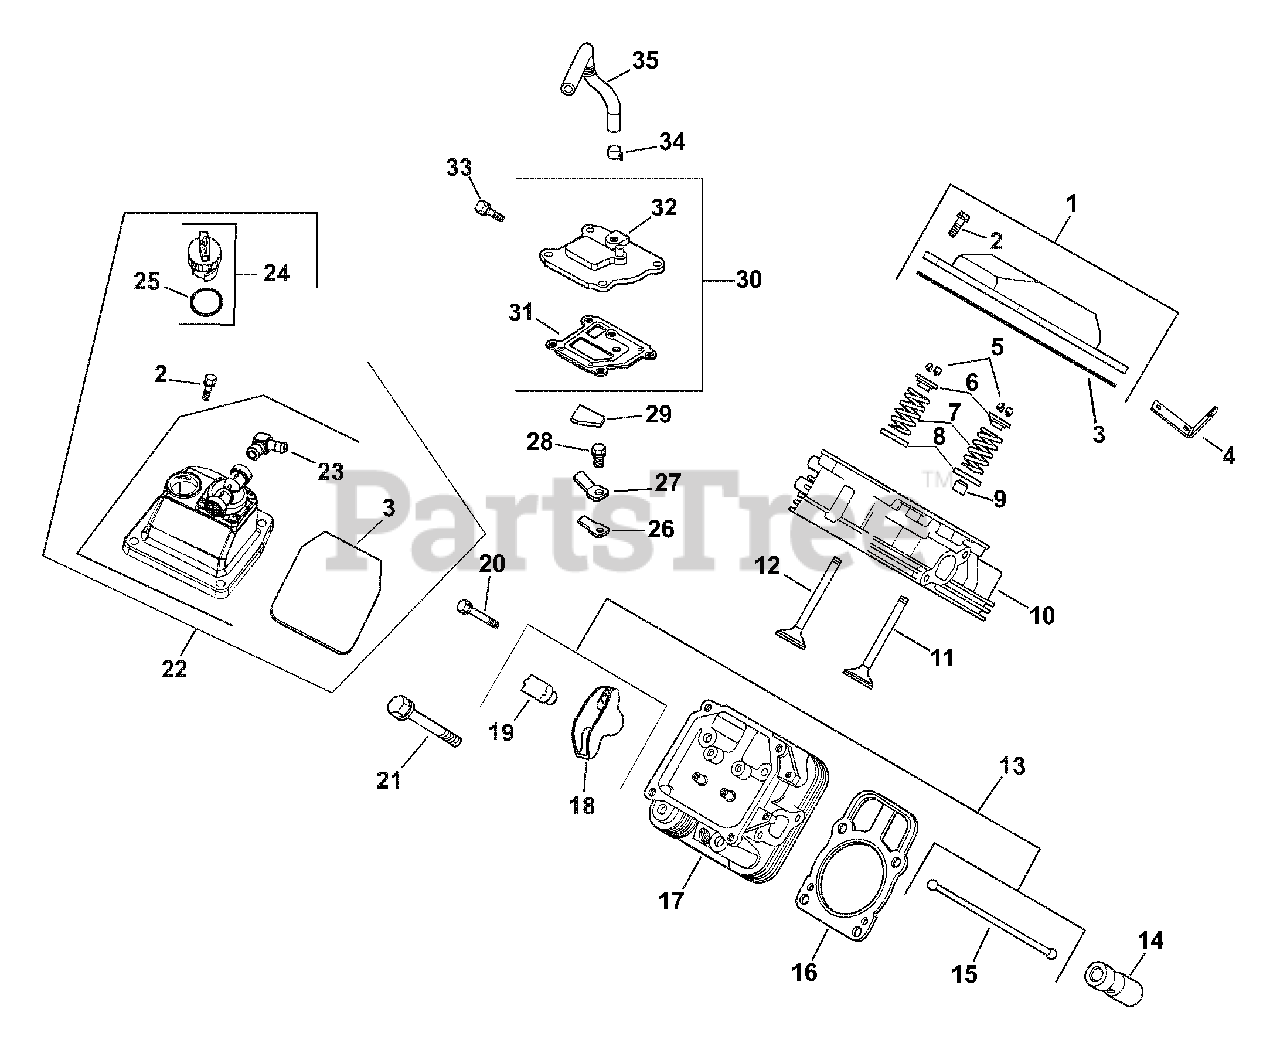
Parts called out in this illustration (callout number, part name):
1	Kit, valve cover - plain
2	Screw, hex. flange M6x1.0x30
3	O-Ring, valve cover
4	Strap, lifting
5	Kit, retainer
6	Cap, valve spring
7	Spring, valve
8	Retainer, spring
9	Seal, valve stem
10	Head assembly, #1 cylinder
11	Valve, intake (Std.)
12	Valve, exhaust (Std.)
13	Kit, valve train
14	Lifter, valve
16	Kit, cylinder head gasket
17	Head assembly, #2 cylinder
19	Pivot, rocker arm
20	Screw, hex. flange M6x1.0x34
21	Screw, hex. flange M10x1.5x90
22	Kit, fuel pump valve
23	Fitting, 90°
24	Cap assembly, oil fill
25	O-Ring
26	Reed, breather
27	Retainer, breather reed
28	Screw, hex. flange M5x0.8x10
29	Filter, breather
30	Kit, breather
31	Gasket, breather
32	Cover, breather
33	Screw, hex. flange M6x1.0x20
34	Clamp, breather
35	Hose, breather
